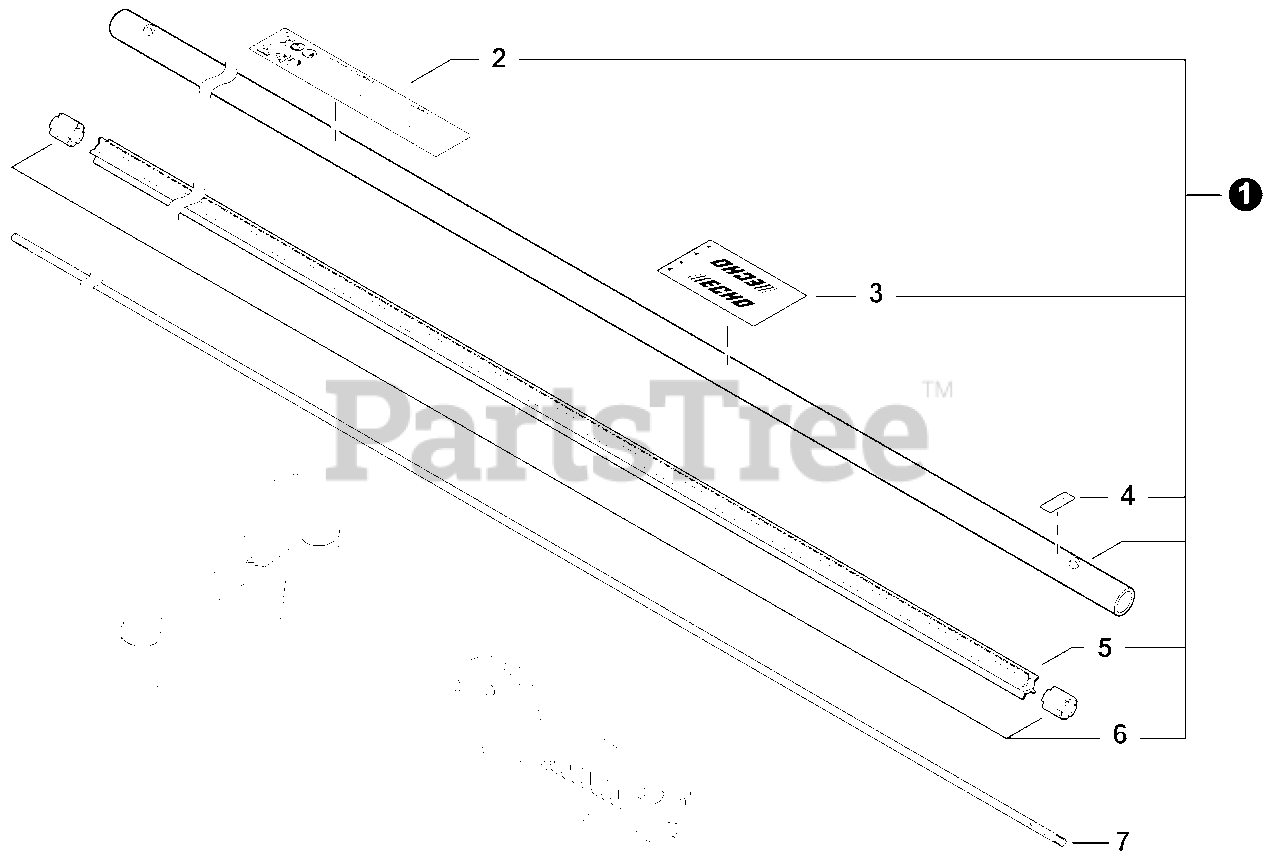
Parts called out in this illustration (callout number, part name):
1	MAIN PIPE ASSY
2	LABEL, CAUTION
3	LABEL, HANDLE LOCATION
4	LABEL - ALIGNMENT
5	LINER, FLEXIBLE 21.6×1420
7	DRIVESHAFT - FLEXIBLE L= 1522
